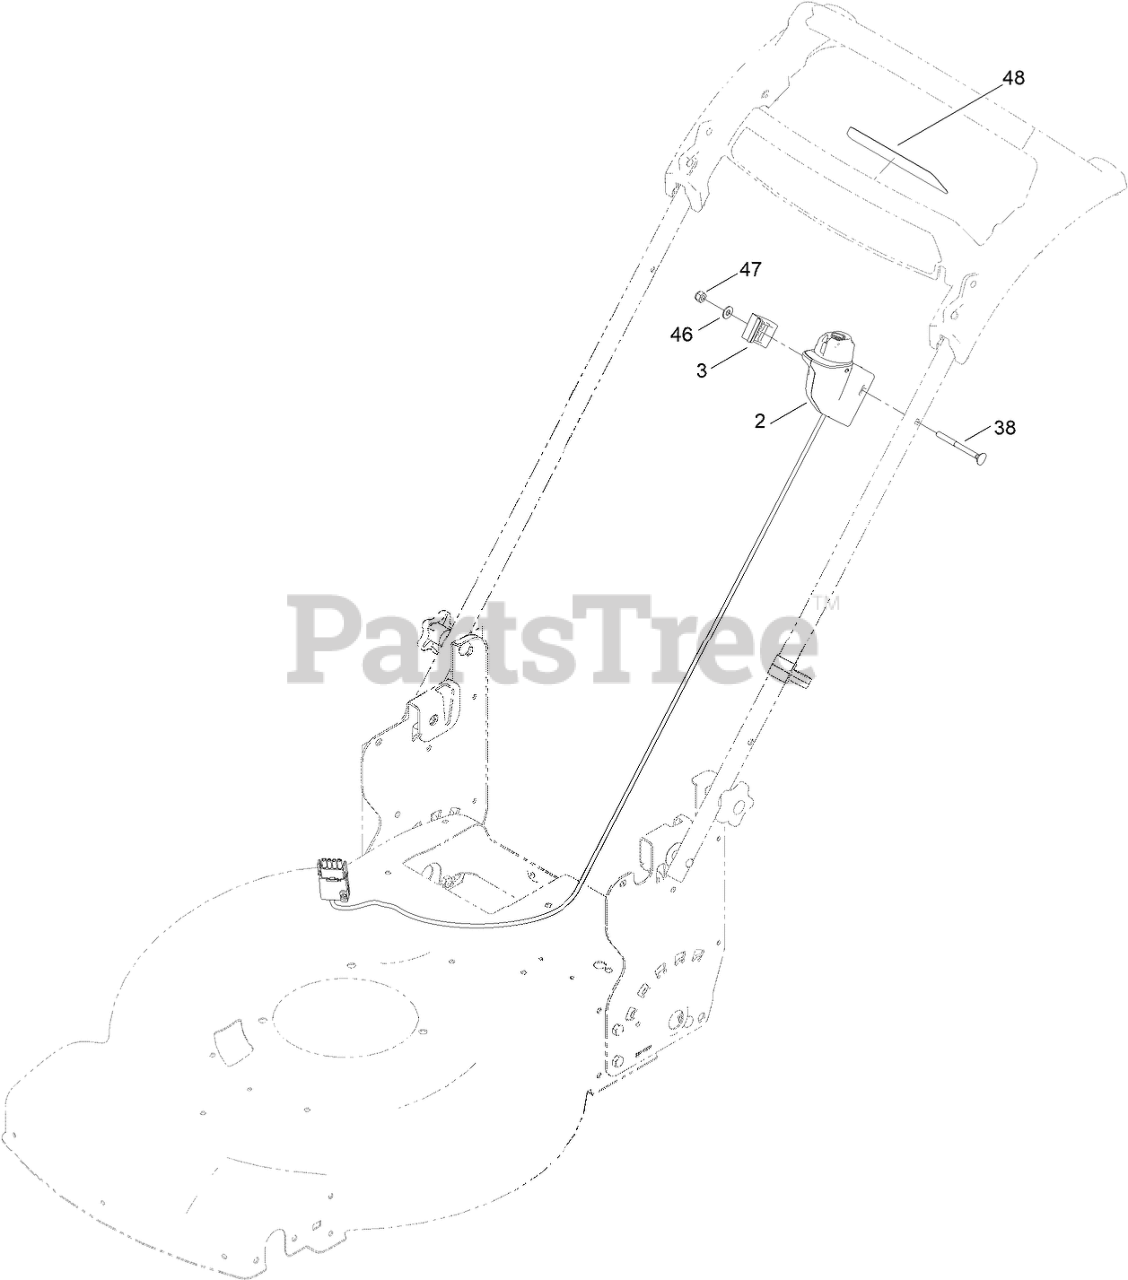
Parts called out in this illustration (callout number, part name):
2	SWITCH-STARTER ASM
3	CLAMP-CABLE
38	SCREW-HANDLE
46	WASHER-FLAT
47	NUT-LOCK, NI
48	DECAL-CONTROLS (60V, START)
